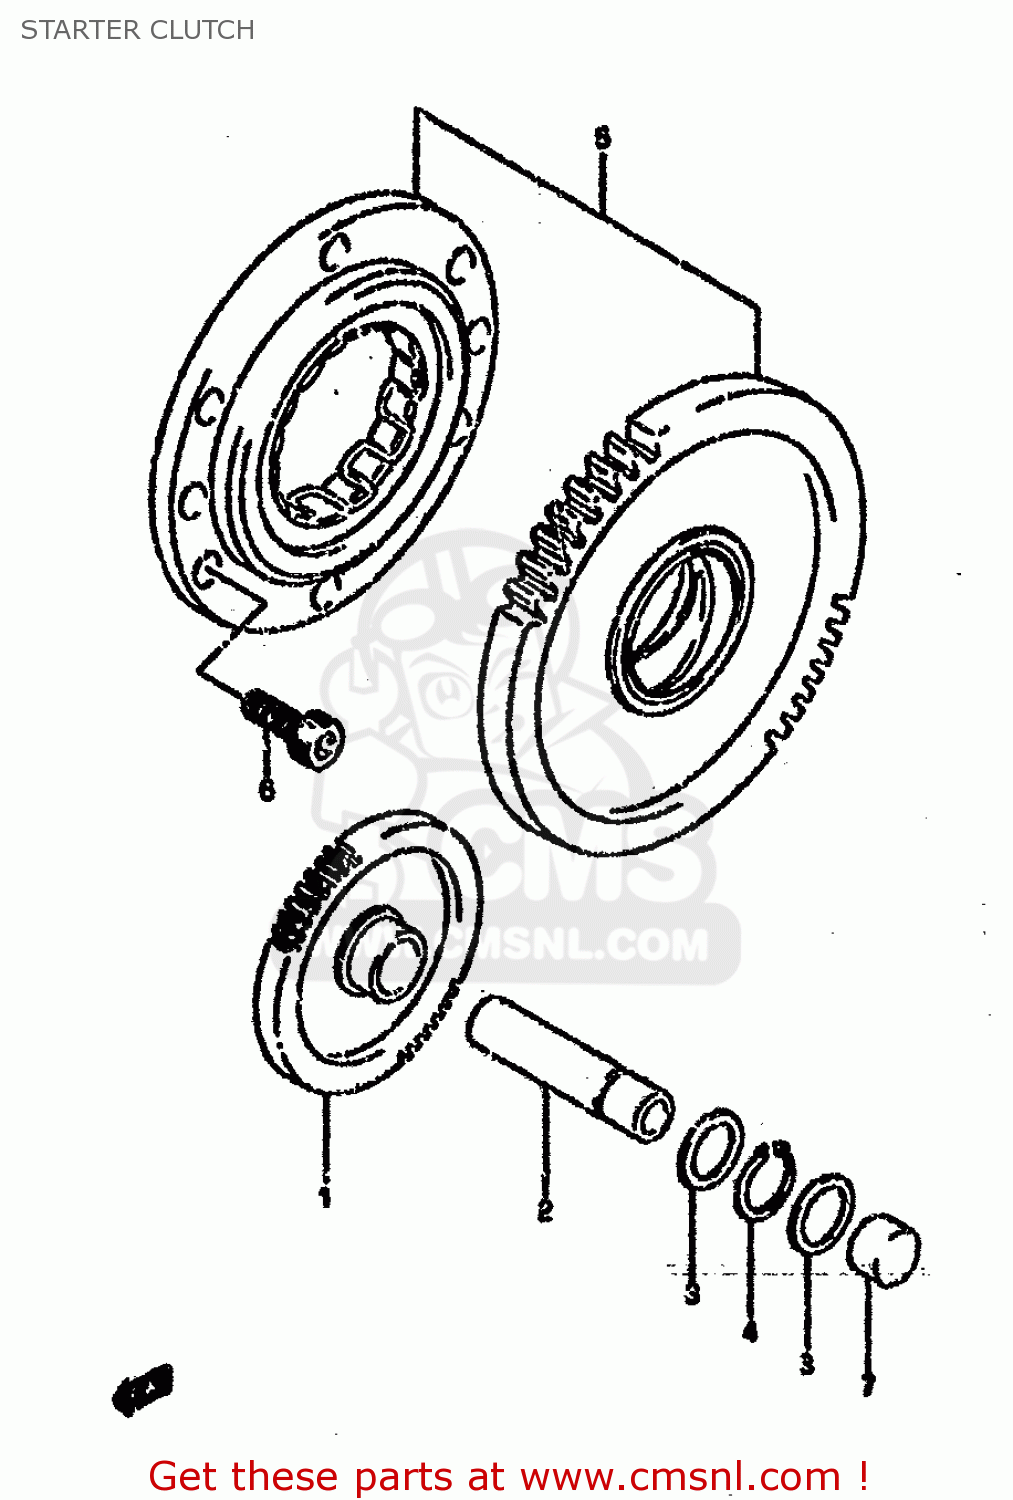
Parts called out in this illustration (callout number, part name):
1	GEAR,STARTER IDLE (NT:1
2	SHAFT,STARTER IDLE GEAR
3	WASHER
4	CIRCLIP,12 MM
5	CLUTCH SET,STARTER
6	BOLT,STRANGER
7	PLUG
